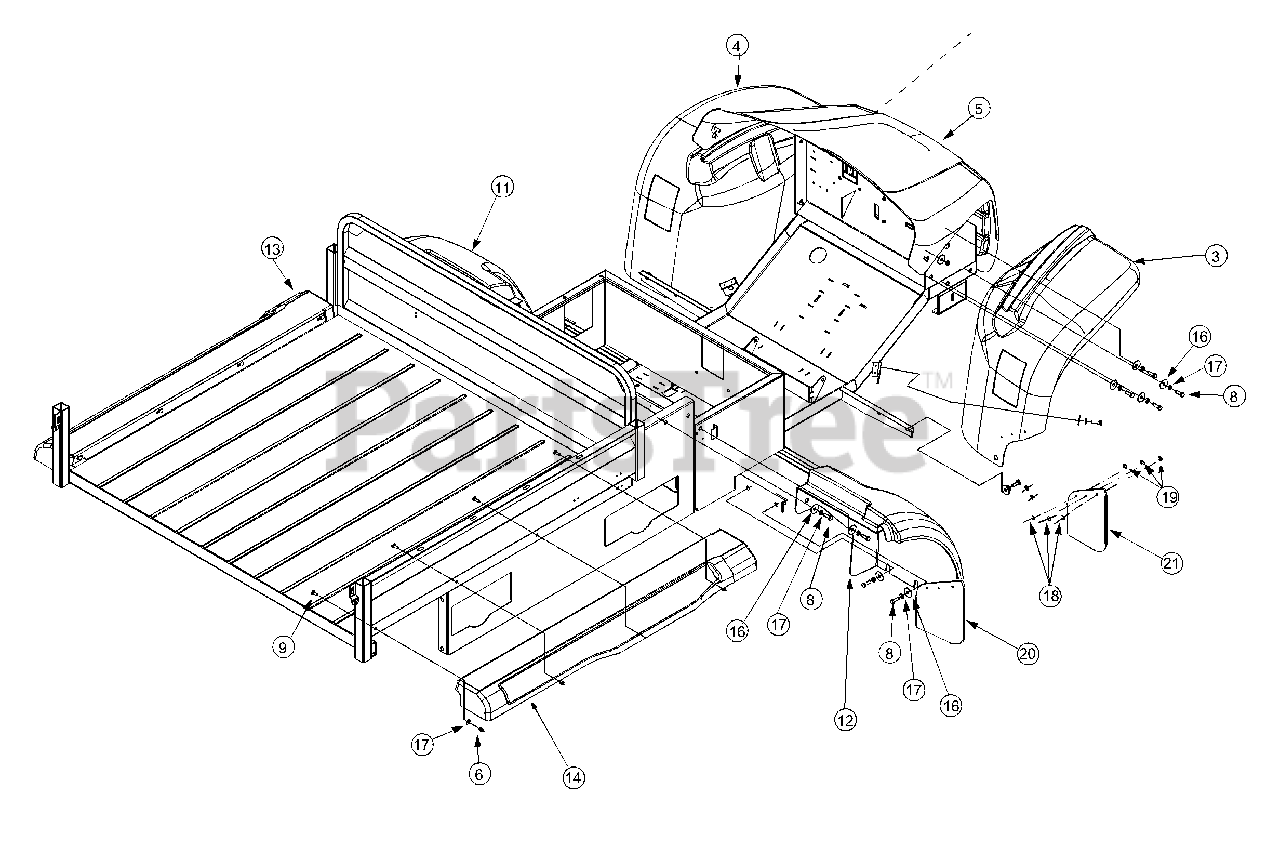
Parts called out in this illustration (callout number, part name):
3	Panel, Front Fender, RH
4	Panel, Front Fender, LH
5	Panel, Hood
6	Hex Lock Nut, Nylon, 1/4-20
8	Hex Screw, 5/16-18 x 1.0 Gr5
9	Hex Screw, 1/4-20 x .75
11	Panel, Rear Fender, LH
12	Panel, Rear Fender,RH
13	Panel, Bed Skirt, LH
14	Panel Bed Skirt, RH
16	Flat Washer, .350 x 1.25 x .06
17	Lock Washer, 5/16
19	Flat Washer, .194 x .62 OD x .063
20	Mud Flap, Rear
21	Mud Flap, Front
